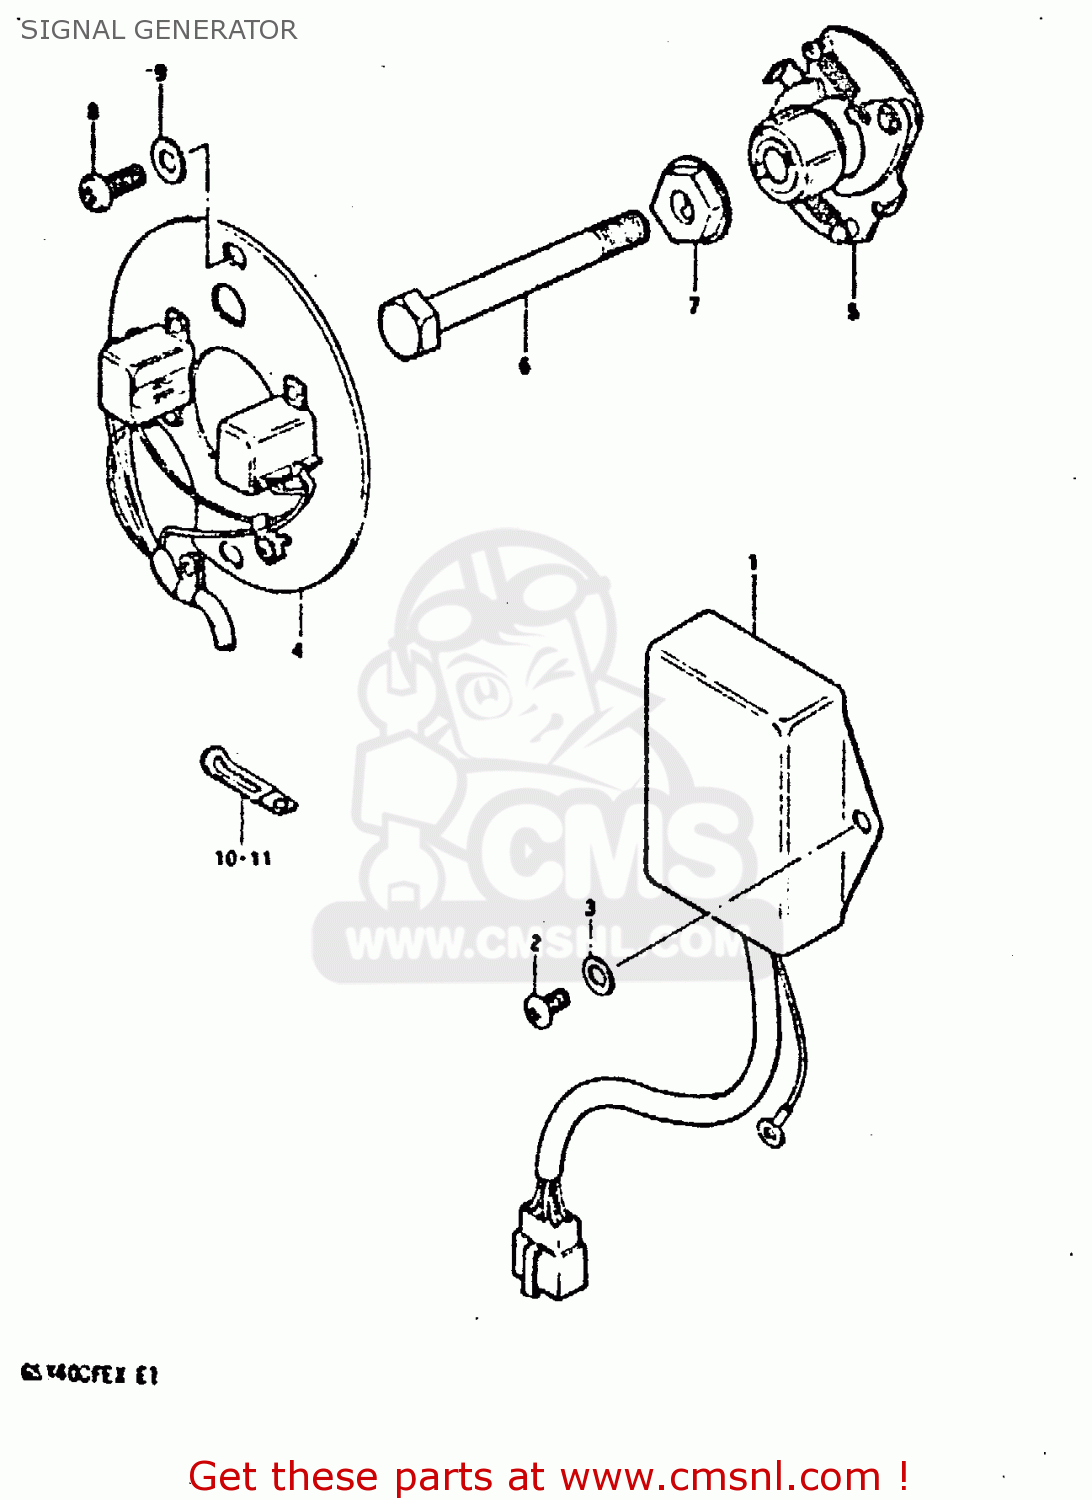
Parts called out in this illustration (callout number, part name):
1	IGNITOR UNIT
2	SCREW
3	WASHER
4	SIGNAL GENERATOR ASSY
5	GOVERNOR ASSY, ADVANCE
6	BOLT
7	WASHER
8	SCREW(5X12)
9	WASHER
10	CLAMP L:35
11	CLAMP
